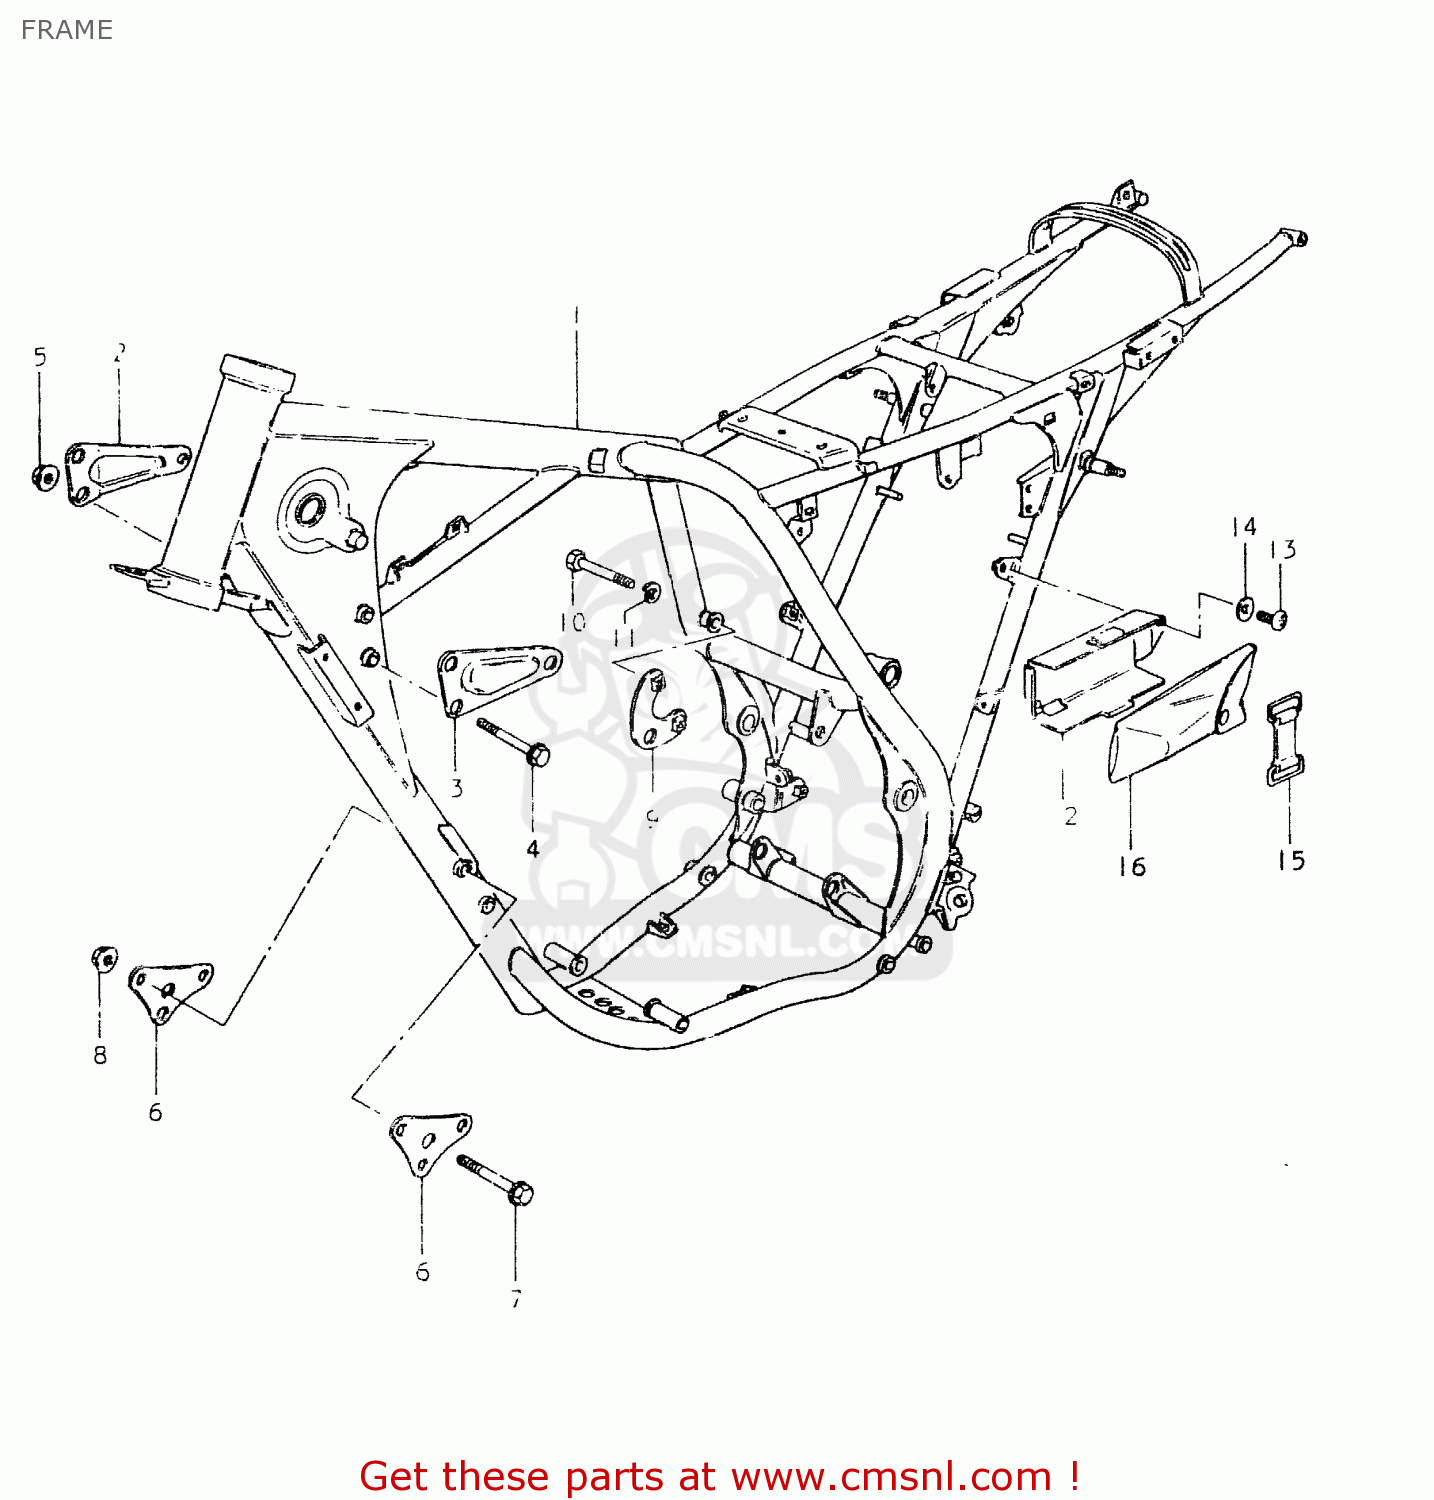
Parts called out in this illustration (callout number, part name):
1	FRAME
2	PLATE COMP,ENGINE MOUNTING
3	PLATE,ENGINE MOUNTING
4	BOLT (6X70)
5	NUT
6	PLATE,ENGINE MOUNTING
7	BOLT (8X70)
8	NUT
9	PLATE,ENGINE MOUNTING
10	BOLT
11	LOCK WASHER
12	HOLDER,TOOL
13	SCREW
14	WASHER 6MM
15	BAND
16	TOOL SET
